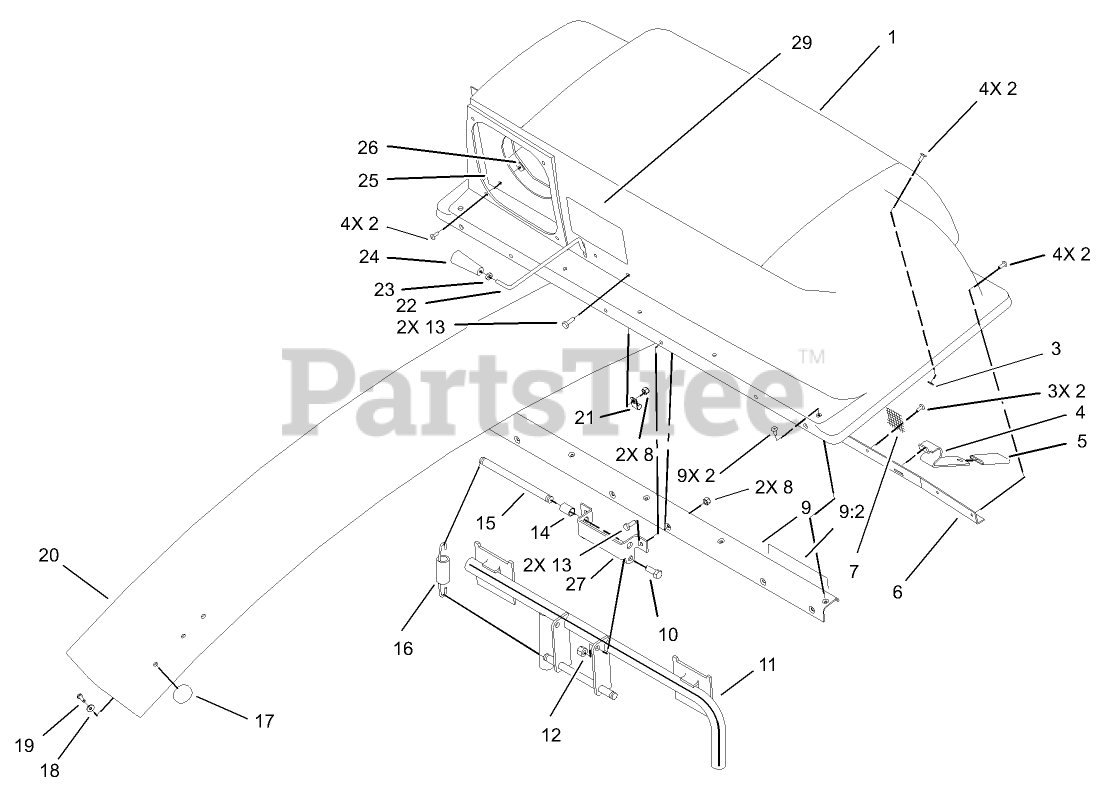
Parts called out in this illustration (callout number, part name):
1	TOP-BAGGER
2	RIVET-BLIND
3	WASHER-FLAT
4	LATCH-BAGGER, TOP
6	SUPPORT-SCREEN
7	SCREEN-BAGGER
8	NUT-LOCK, NI
9	STIFFENER ASM
9:2	DECAL-CAUTION
10	SCREW-HH
11	FRAME ASM
12	NUT-LOCK, NI
13	SCREW-HH
14	SPACER
15	PIN-SPRING
16	SPRING-EXTENSION
18	WASHER-PLAIN
19	SCREW-PPHTF
20	CHUTE-DISCHARGE
21	CLAMP
22	FEELER-FILL, BAG
23	NUT-JAM
24	HANDLE-TAPERED
25	SEAL-CHUTE
26	HINGE-BAG, TOP
27	CLAMP-SEAL
29	DECAL
